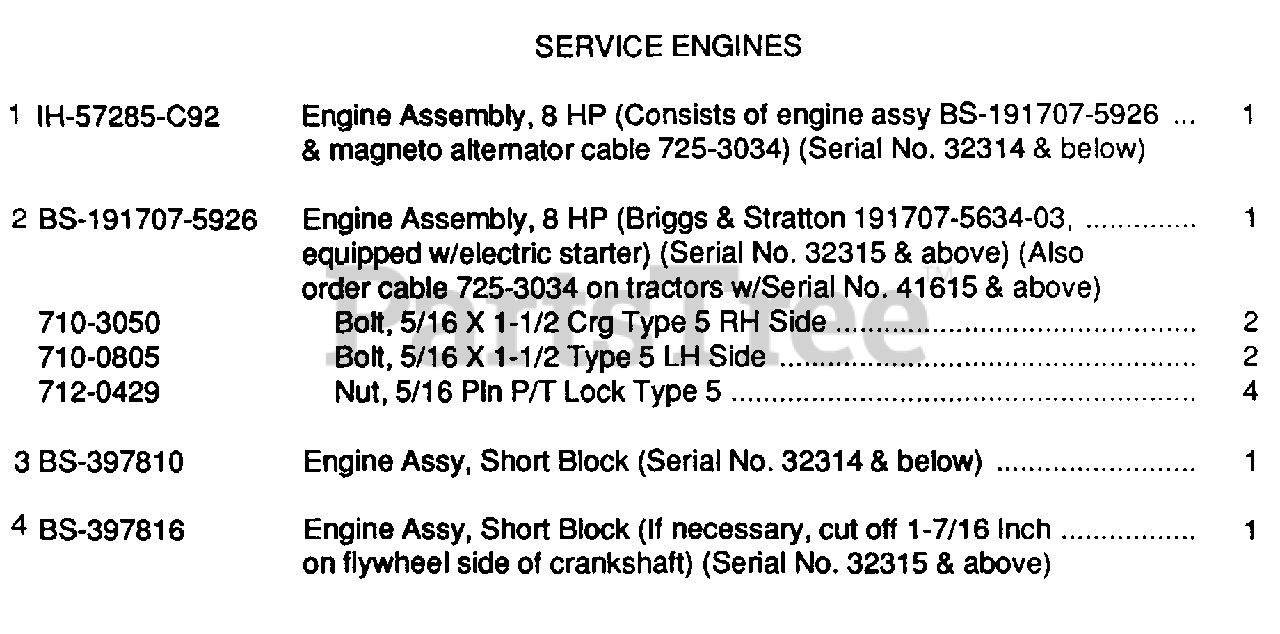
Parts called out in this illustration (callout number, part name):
1	Engine Assembly, 8 HP
2	Engine Assembly, 8 HP
3	Engine Assy, Short Block
4	Engine Assy, Short Block
